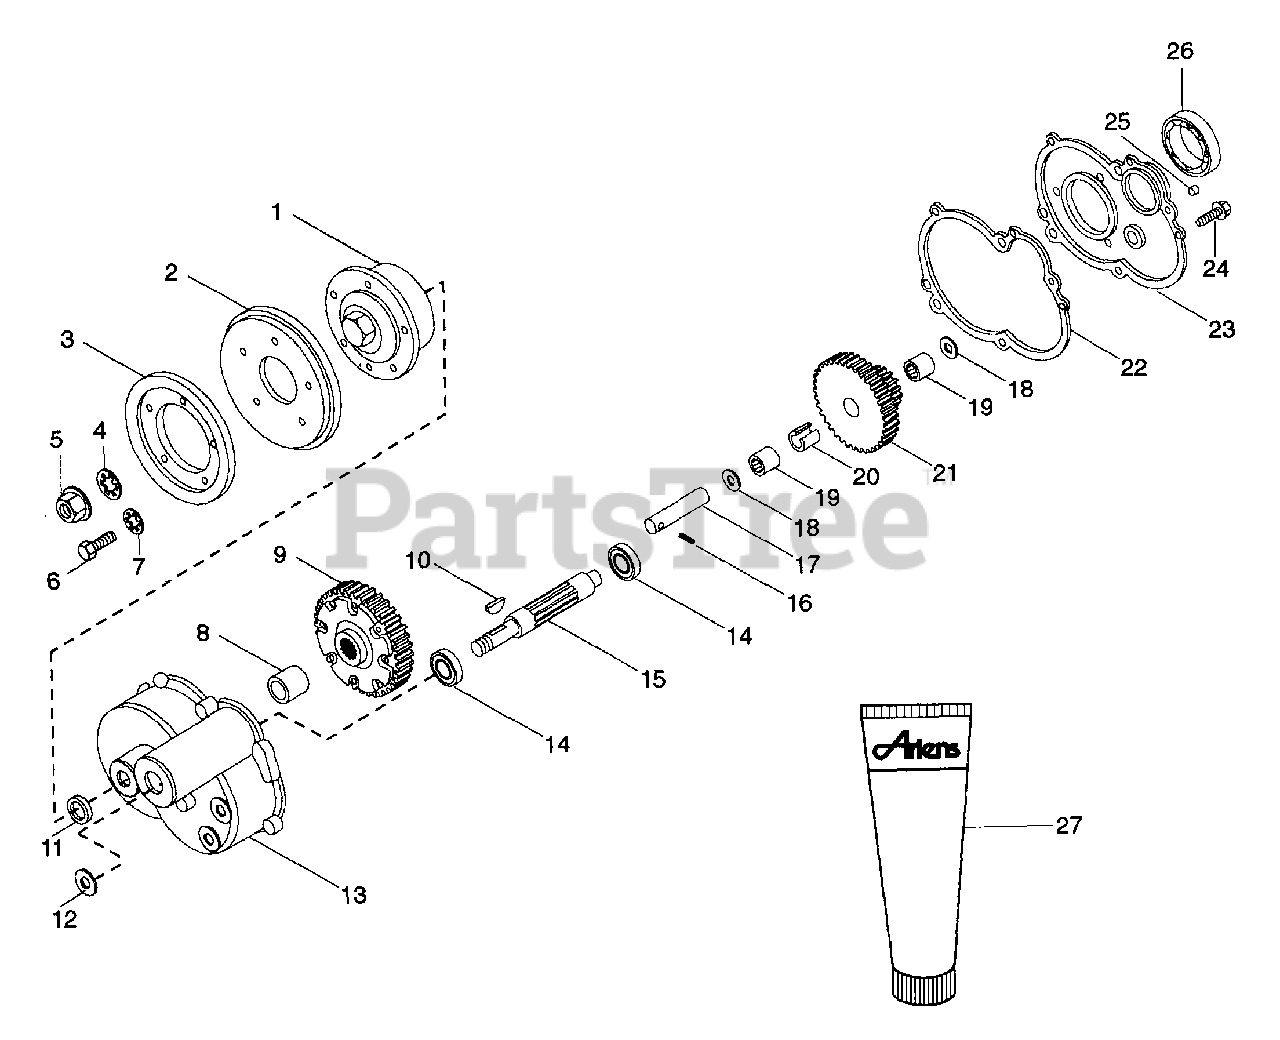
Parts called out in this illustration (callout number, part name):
1	FRICTION DISC HUB
2	FRICTION DISC
4	WSHR-LK-INT .625X.045 PL
5	NUT-LK-NYL.625-18 PL
6	BLT-HEX .31-18X.50 PL GR2
7	WSHR-LK-INT .313X.030 PL
8	BSHG-SLV .875X1.125X1.046
9	DIFFERENTIAL ASSEMBLY
10	KEY-WDRF .188X.875X.375 SAE11
11	SEAL .875X1.125X.125
12	WSHR-FL-STL .627X.990X.032
13	SERVICE GEAR CASE
14	BRG-BALL .625X1.375X.44
15	PINION SHAFT
16	PIN-ROLL .125X.75
17	IDLER SHAFT
18	WSHR-FL-STL .505X.875X.024 PL
19	BRG-NEEDLE .50X.688X.625
20	SPACER - CUT .640X.688X.625
21	PINION & GEAR W/BEARING ASSEMB
23	GEAR CASE COVER ASSEMBLY
24	SCR-TAP 10-24X1.0 HWH PL TR
25	BREATHER
26	BRG-BALL 1.125X2.50X.63
27	MULTIPURPOSE GREASE
